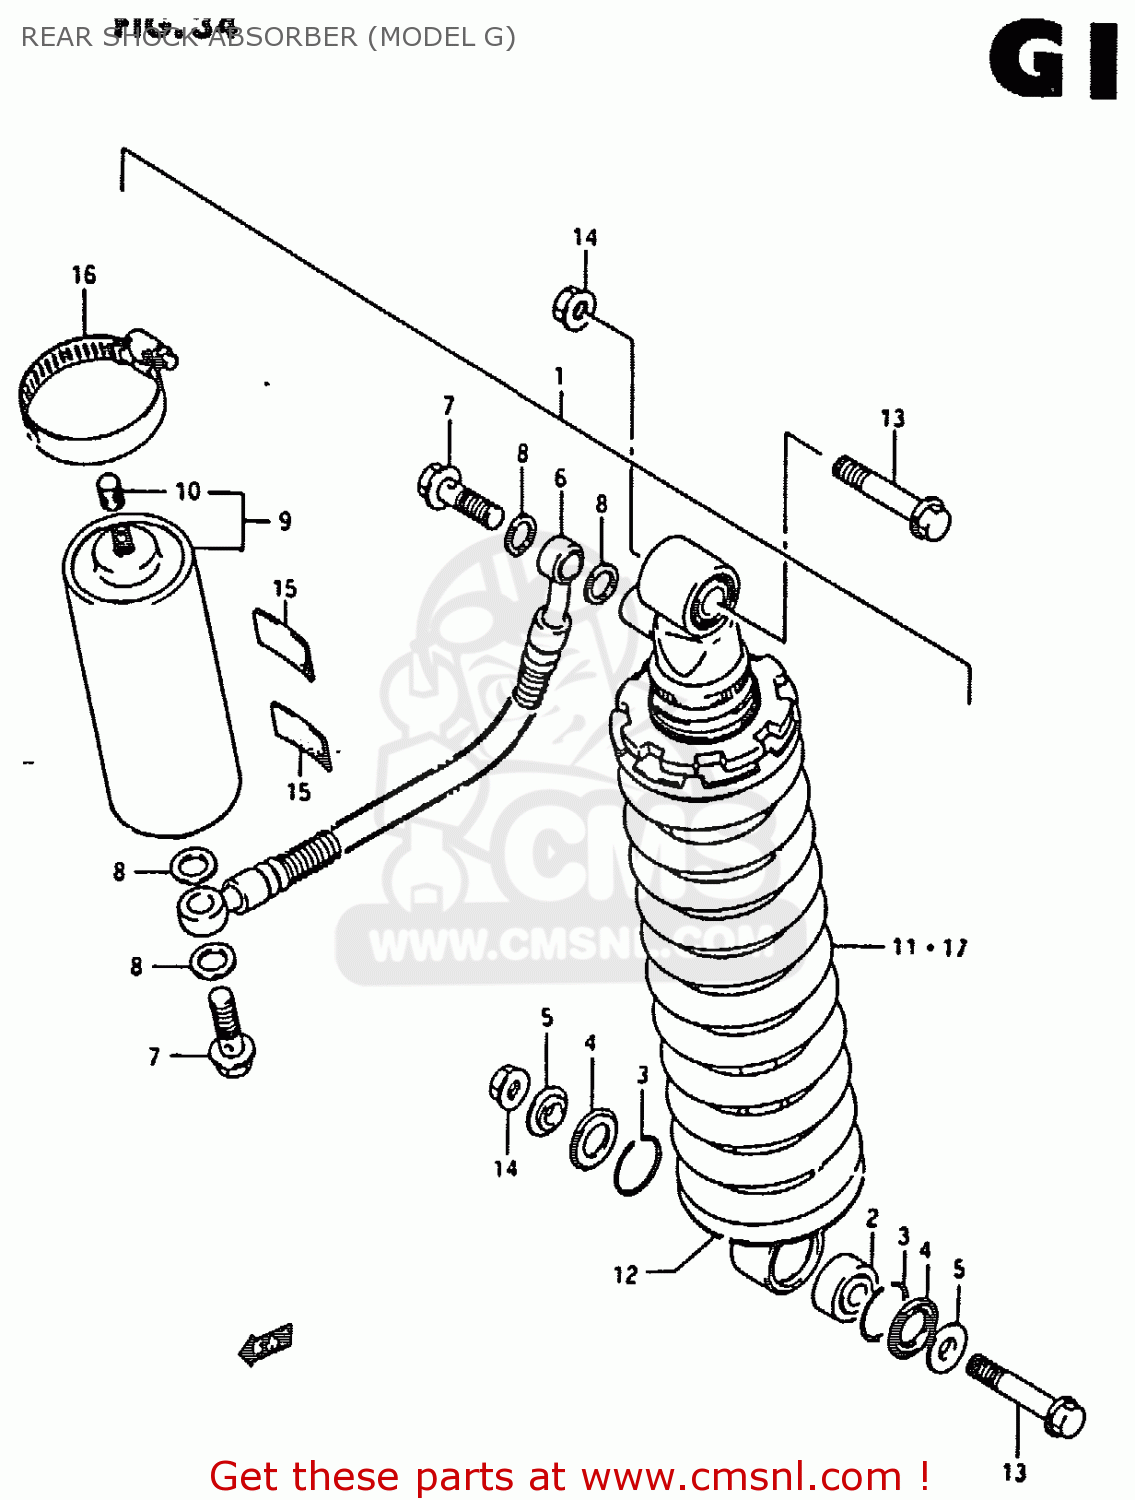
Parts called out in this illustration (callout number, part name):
1	ABSORBER ASSEMBLY,REAR SHOCK
2	BEARING,REAR SHOCK ABSORBER
3	RING
4	DUST SEAL,RR SHOCK
5	COLLAR
6	HOSE
7	BOLT,REAR SHOCK ABSORBER
8	WASHER(10X15X1.5)
9	RESERVE TANK,REAR SHOCK
10	CAP,VALVE AIR
11	SPRING
12	SEAT, SPRING
13	BOLT,RR CUSHION ROD UPR
14	NUT
15	CUSHION,REAR SHOCK ABSORBER
16	CLAMP
17	SPRING,REAR SHOCK ABSORBER
